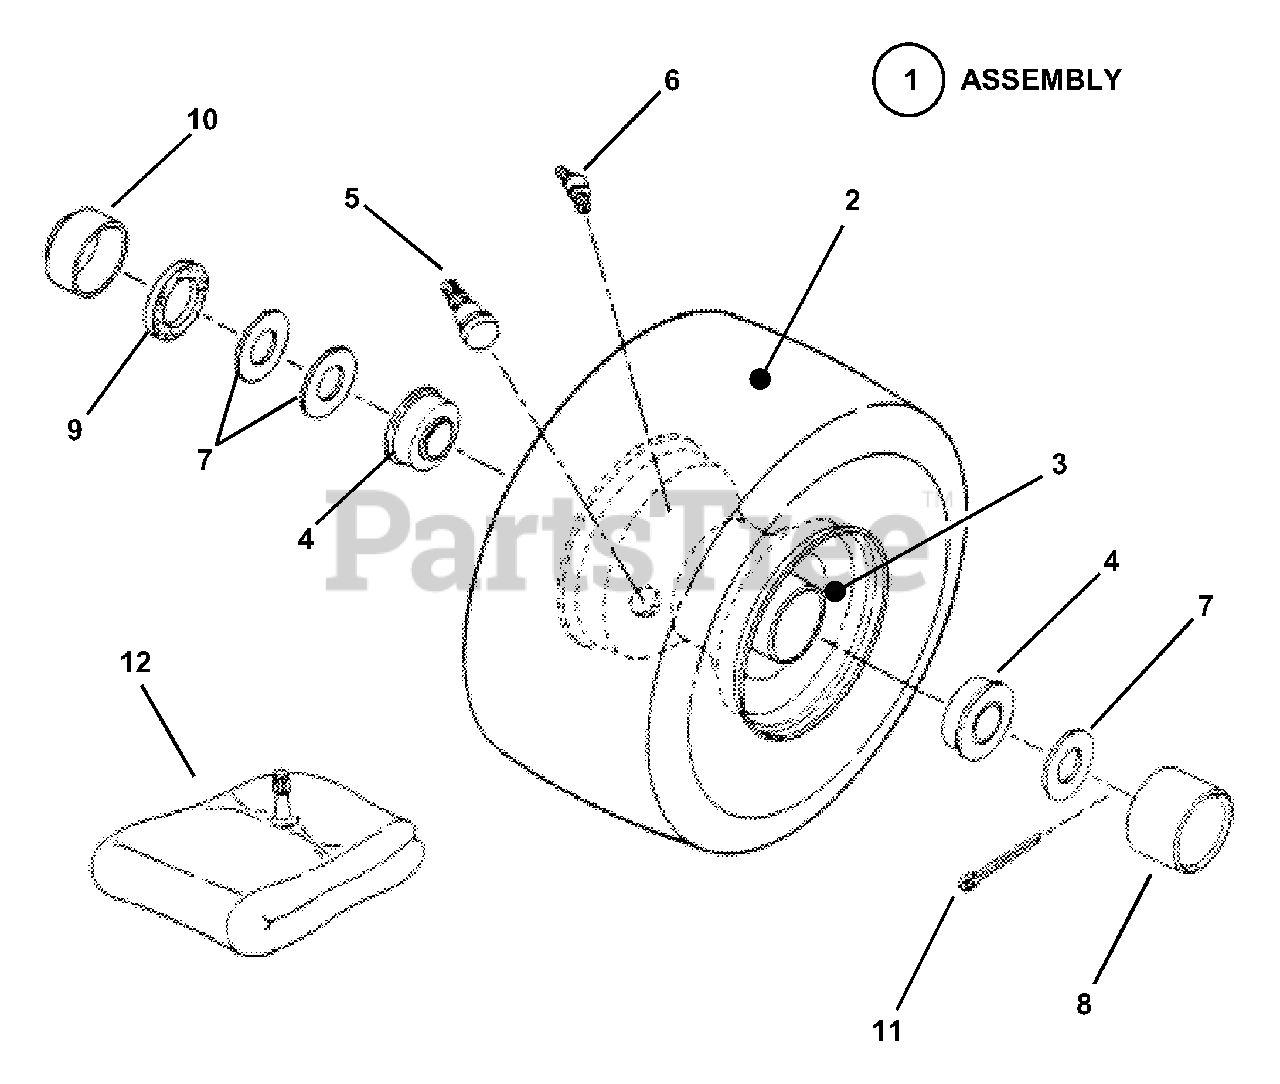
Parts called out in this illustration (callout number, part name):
1	ASSEMBLY, Front Tire & Rim
2	TIRE, 11 x 4.00-4 (Kenda)
3	RIM
4	BEARING, Ball
5	VALVE, Air (Snap-in)
6	FITTING Lube
7	WASHER, 3/4" I.D.
8	CAP, Hub
9	SEAL, Felt
10	CAP, Dust
11	PIN, Cotter 5/32 x 1"
12	TUBE, Inner
